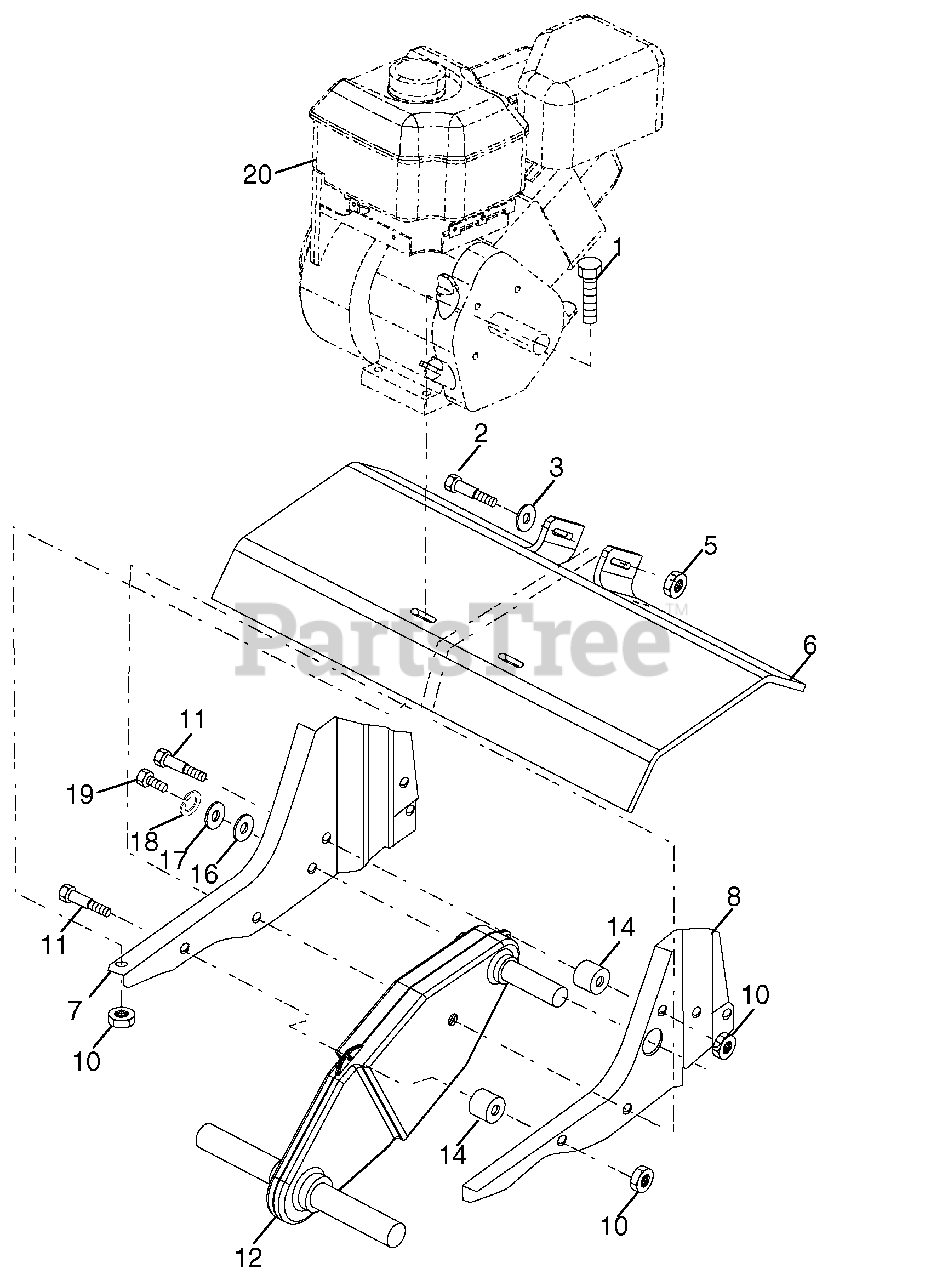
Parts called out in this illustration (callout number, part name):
1	Bolt, Hex Head, 5/16-18 x 1-1/2 Gr. 2
2	Bolt, Hex Head, 3/8-16 x 3-1/4
3	Washer, 3/32 x 13/16 x 11
5	Nut, Hex, Flangelock 3/8-16
6	Shield, Tine
7	Bracket, Engine, R.H.
8	Bracket, Engine, L.H.
10	Nut, Hex, Flangelock
11	Bolt, Shoulder
12	Transmission
14	Spacer, Split
16	Washer, 9/32 x 7/8 x 12 Ga.
17	Washer, 9/32 x 1-1/4 x 16 Ga.
18	Washer, Lock 1/4
19	Bolt, Hex Head, 1/4-28 x 3/4 Gr. 5
